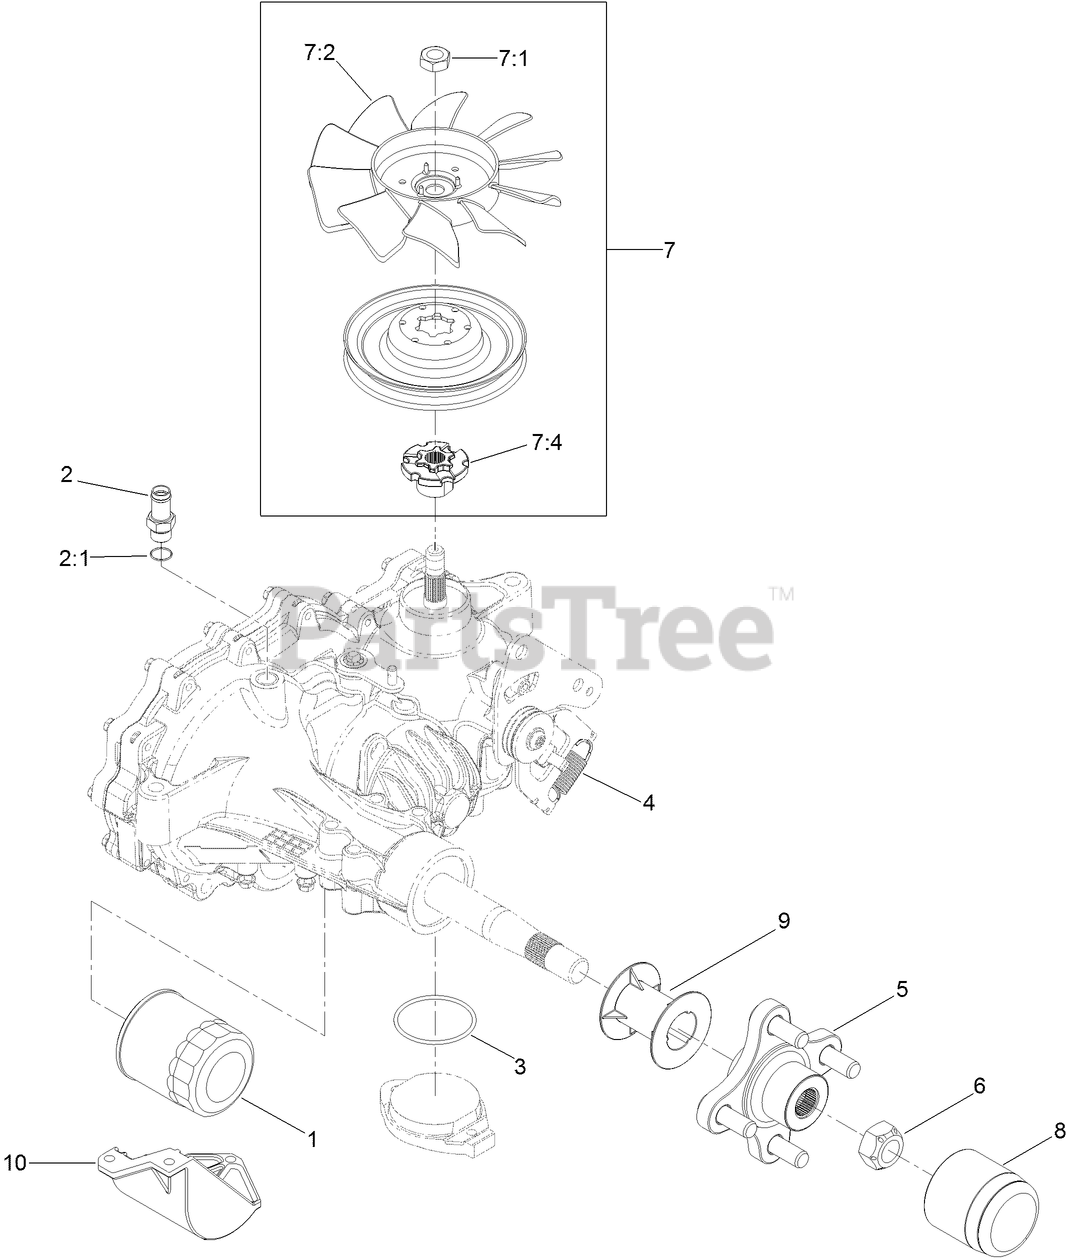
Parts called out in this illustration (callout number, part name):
1	ELEMENT-OIL FILTER, HYD
2	ADAPTER-STRAIGHT
2:1	O-RING
3	O RING-SEAL
4	SPRING-EXTENSION
5	HUB-OFFSET
6	NUT-HUB
7	FAN AND PULLEY KIT
7:1	NUT-HJ
7:4	HUB-PULLEY
8	CAP-AXLE, LONG
9	TUBE-AXLE
10	GUARD-FILTER, RH
